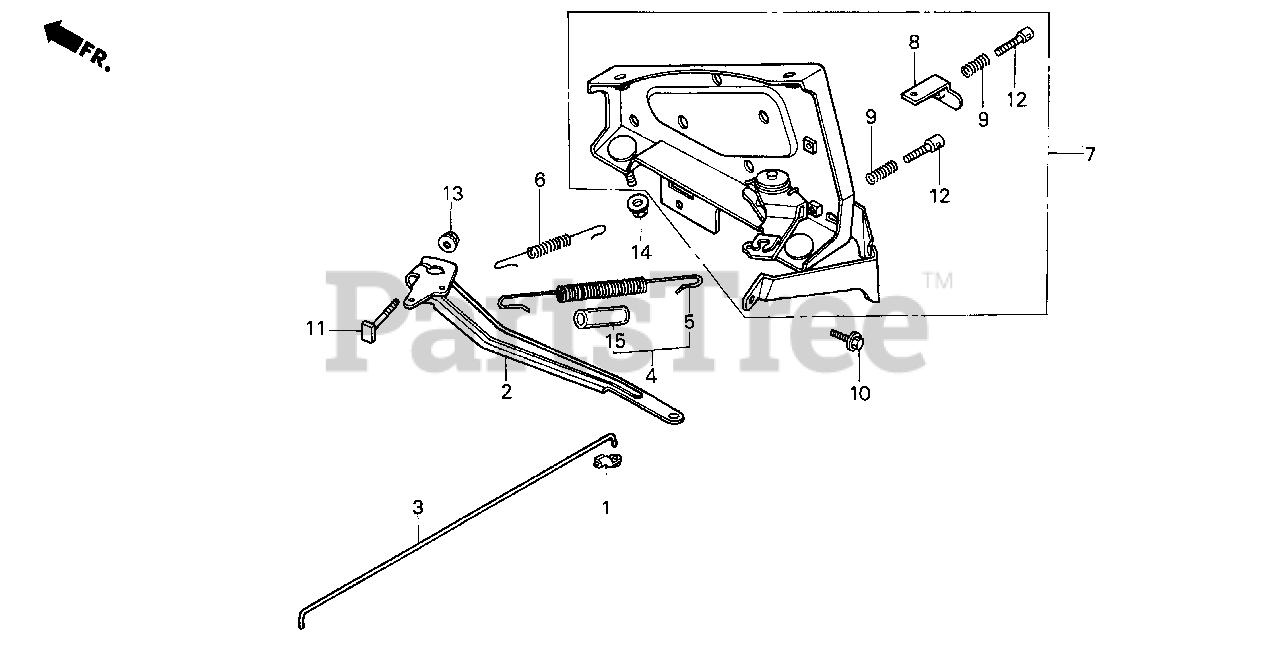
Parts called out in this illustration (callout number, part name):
1	JOINT, ROD
2	ARM, GOVERNOR
3	ROD, GOVERNOR
4	SPRING ASSY., GOVERNOR
5	SPRING, GOVERNOR
6	SPRING, GOVERNOR IDLE
7	CONTROL ASSY.
8	PLATE, CONTROL
9	SPRING, CONTROL ADJUSTING
10	BOLT, FLANGE (6X12) (CT200)
11	BOLT, GOVERNOR ARM
12	SCREW, LOCK PAN
13	NUT, FLANGE (6MM)
14	NUT, FLANGE (8MM)
15	BULK HOSE, VINYL (9X11X3000) (9X11X30)
